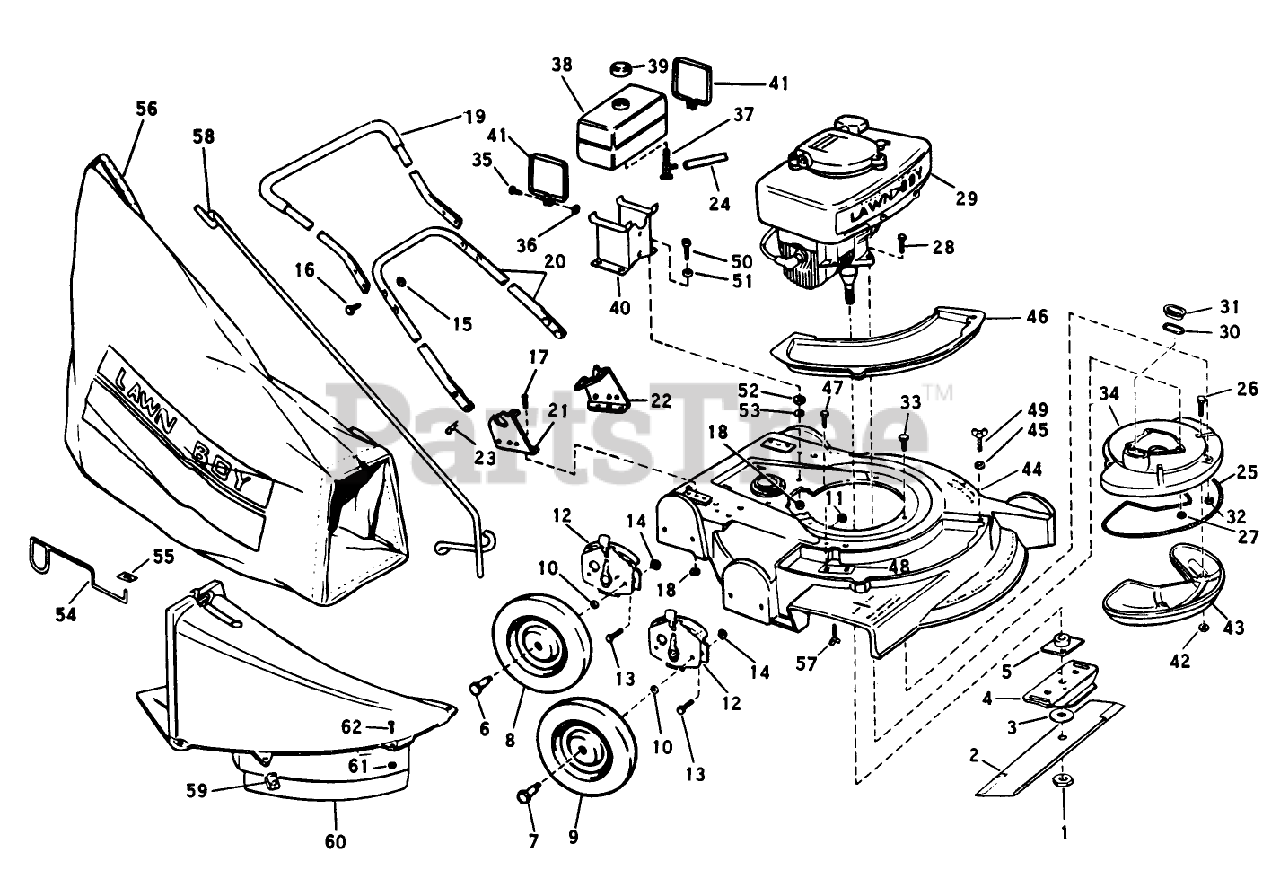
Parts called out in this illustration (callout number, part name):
1	NUT-BLADE
5	PLATE AND COLLAR ASM
6	BOLT-SHOULDER
7	BOLT WHEEL
10	WASHER WROUGHT
15	STOP NUT
17	SCREW S
19	Handle Grip Assy. Top
30	GASKET S
37	VALVE&SCREEN SM
42	LOCKNUT E
56	89802 LB WHOLE GOODS
59	SPEED NUT ARDEN
60	Chute Skirt Assembly (Includes Hardware)
